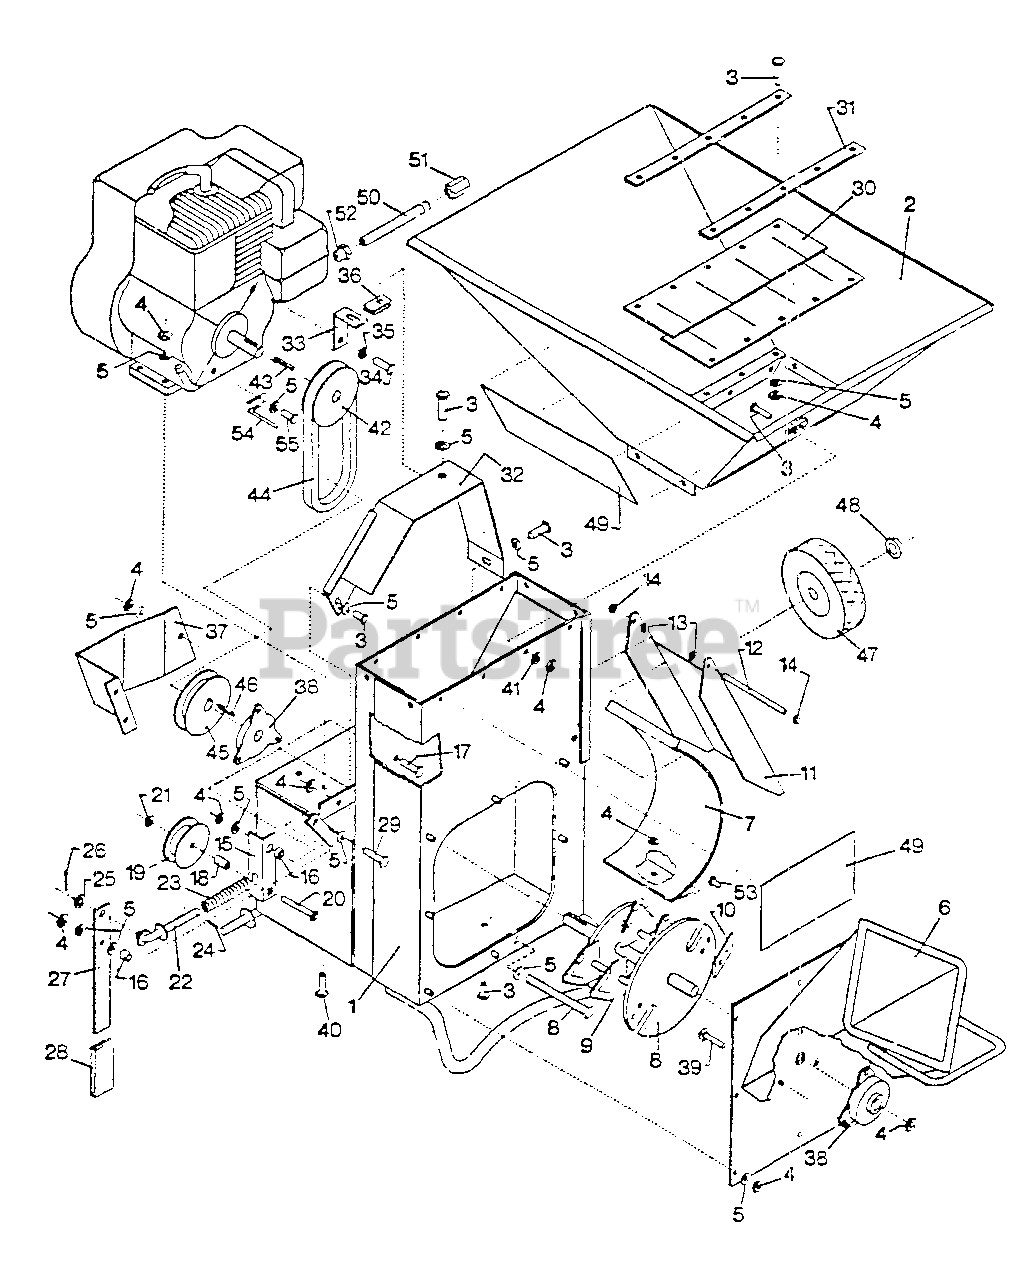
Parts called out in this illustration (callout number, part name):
7	GRATES
16	SPACER, IDLER PIVOT
49	LABEL - MODEL SH-3000
49	LABEL - MODEL SH-5000
49	LABEL - MODEL SH-8000E
